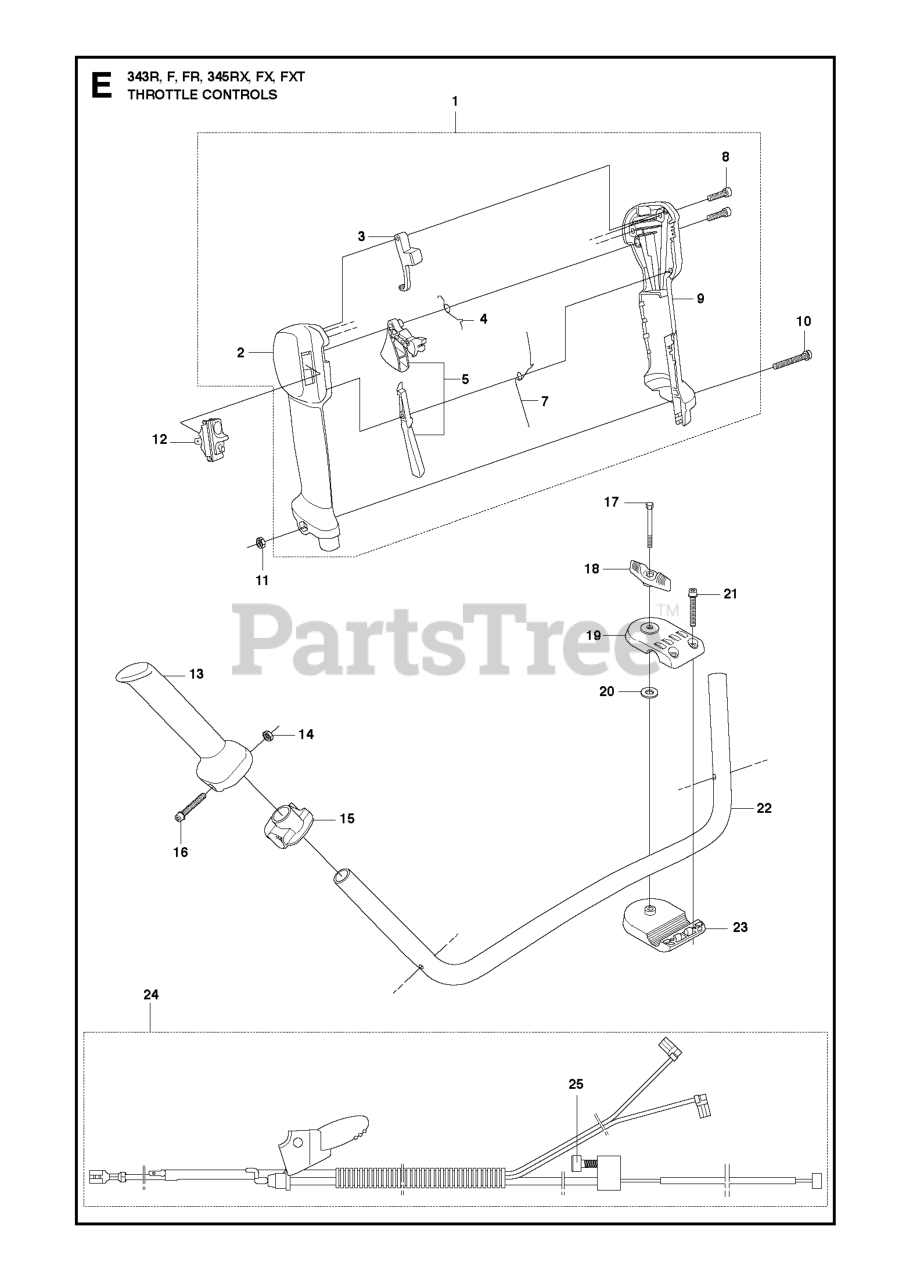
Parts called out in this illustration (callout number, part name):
1	THROTTLE HANDLE ASSY
2	HANDLE HALF LEFT
3	LOCKOUT STARTER THROTTLE
5	THROTTLE CONTROL
9	HANDLE HALF RIGHT
10	SCREW
12	STOP BUTTON
14	NUT M6M M5
17	%SCREW
19	HANDLE HOLDER UPPER
23	HANDLE HOLDER LOWER
24	WIRING ASSY
25	SCREW
